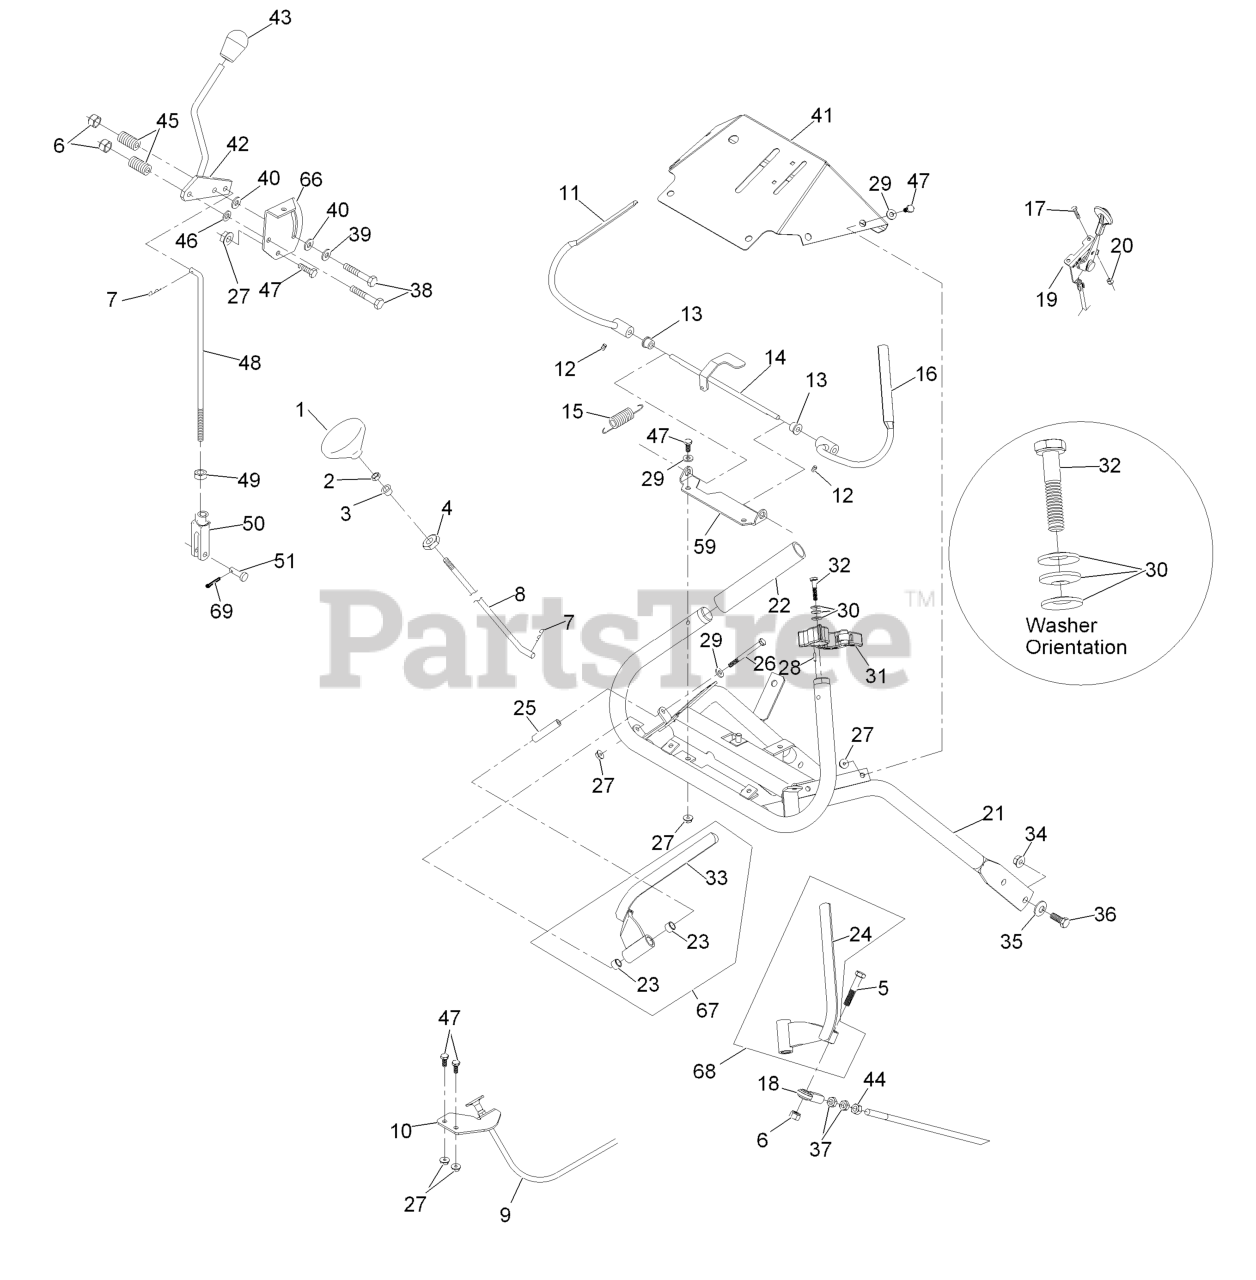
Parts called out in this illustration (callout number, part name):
1	KNOB-PUSH / PULL
2	NUT-JAM
3	BEARING-NYLON
4	NUT-PUSH
5	SCREW-HH
6	NUT-LOCK, NI
7	PIN-COTTER
8	LINKAGE,BLADE PUSH/PULL
9	CABLE-CHOKE
10	BRACKET-CABLE, CHOKE
12	SCREW-SET
13	BUSHING-NYLON
14	WLD,OPC LEVER AXLE
15	SPRING-EXTENSION
16	WLD,RH OPC LEVER
17	BOLT-CARR
18	JOINT-BALL, END
19	CONTROL, THROTTLE
20	NUT-LOCK, NI
21	WLD,VH ECS HANDLE
22	GRIP-BAR, HANDLE
23	BUSHING-SLEEVE
24	Lever, Drive Lh
25	BUSHING-LEVER, DRIVE
26	SCREW-HH
29	WASHER-FLAT
30	WASHER-SPRING
31	ASM,LATCH RH THUMB
31	ASM,LATCH LH THUMB
32	SCREW-HH
33	Lever, Drive Rh
34	NUT-HHF, WHIZ
35	WASHER-BELLEVILLE
36	SCREW-HH
37	NUT-HJ
38	SCREW-HH
39	WASHER-FRICTION
40	WASHER-FRICTION
41	ASM,CONSOLE W/DECALS
43	KNOB, FE.LCKG. BLACK
44	NUT-HEX
45	SPRING-COMPRESSION
46	WASHER-PLAIN
47	SCREW-HH
48	ROD-CONTROL, SPEED
49	NUT-JAM
50	YOKE-ADJUSTABLE
51	PIN-CLEVIS
59	BRACKET,OPC AXLE
66	BRACKET,SHIFTER SLIDE (PL
67	DRIVE LEVER-ASM, RH
68	DRIVE LEVER-ASM, LH
69	PIN-COTTER
